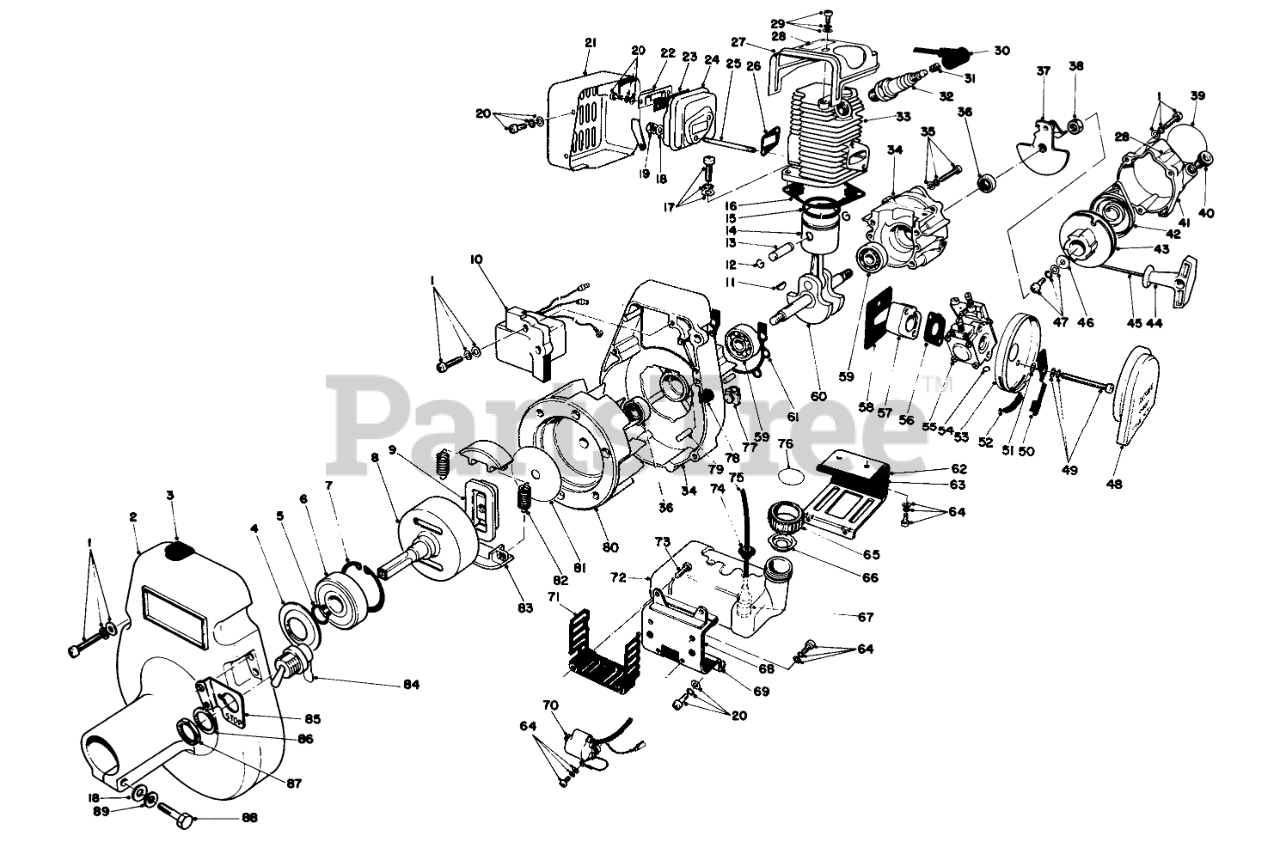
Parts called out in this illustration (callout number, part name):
1	SCREW
2	Fan Cover
4	Stopper
5	Circlip
6	Ball Bearing
7	Circlip
8	Clutch Drum
9	Clutch Boss
10	MODULE CDI-WILLMAR
11	Woodruff Key
12	Circlip, Piston Pin
13	Piston Pin
14	Piston
15	PISTON RING
16	Gasket, Cylinder Base
17	SCREW W/WASHER
18	WASHER
20	SCREW
21	Muffler Cover
22	Lid-Muffler
23	Screen
24	Muffler Body
25	STUD BOLT
26	Gasket, Muffler
27	Cylinder Cover
28	Decal-Hot Surface
29	SCREW
30	Cap-Spark Plug
31	Coil Spring-Plug Cap
33	Cylinder
34	Crankcase Set
35	SCREW
36	Oil Seal
37	Ratchet Assembly
39	Decal
40	Rope Guide
41	Starter Case
42	REWIND SPRING
43	Recoil Drum
44	Starter Handle
45	Rope-Starter
46	WASHER-WILLMAR
47	Screw
48	AIR FILTER
49	SCREW
50	CHOKE SHUTTER
51	CHOKE SHUTTER SPACER
52	Grommet
53	Case-Air Cleaner
54	Clip Fuel Pipe
55	Carburetor Assembly
56	GASKET
57	Insulator
58	INSULATOR GASKET-WILLMAR
59	Bearing
60	Crankshaft Assembly
61	Gasket-Crankcase
62	Bracket-Fuel Tank
63	Cushion
64	Screw
65	Cap-Fuel Tank
66	Check Valve
67	FUEL STRAINER
68	Cushion
69	Bracket-Fuel Tank
70	IGNITION COIL-WILLMAR
71	Dust Filter
72	FUEL TANK
73	Screw
74	Grommet
75	Fuel Line
76	Decal Fuel Mix
77	Cord Holder
78	Grommet
79	Knockpin
80	Flywheel
81	Side Plate
82	CLUTCH SPRING
83	CLUTCH SHOE
84	Switch (Incl. Ref. #86 & 87)
85	Bracket-Switch
86	Washer
87	Nut
89	Lockwasher
